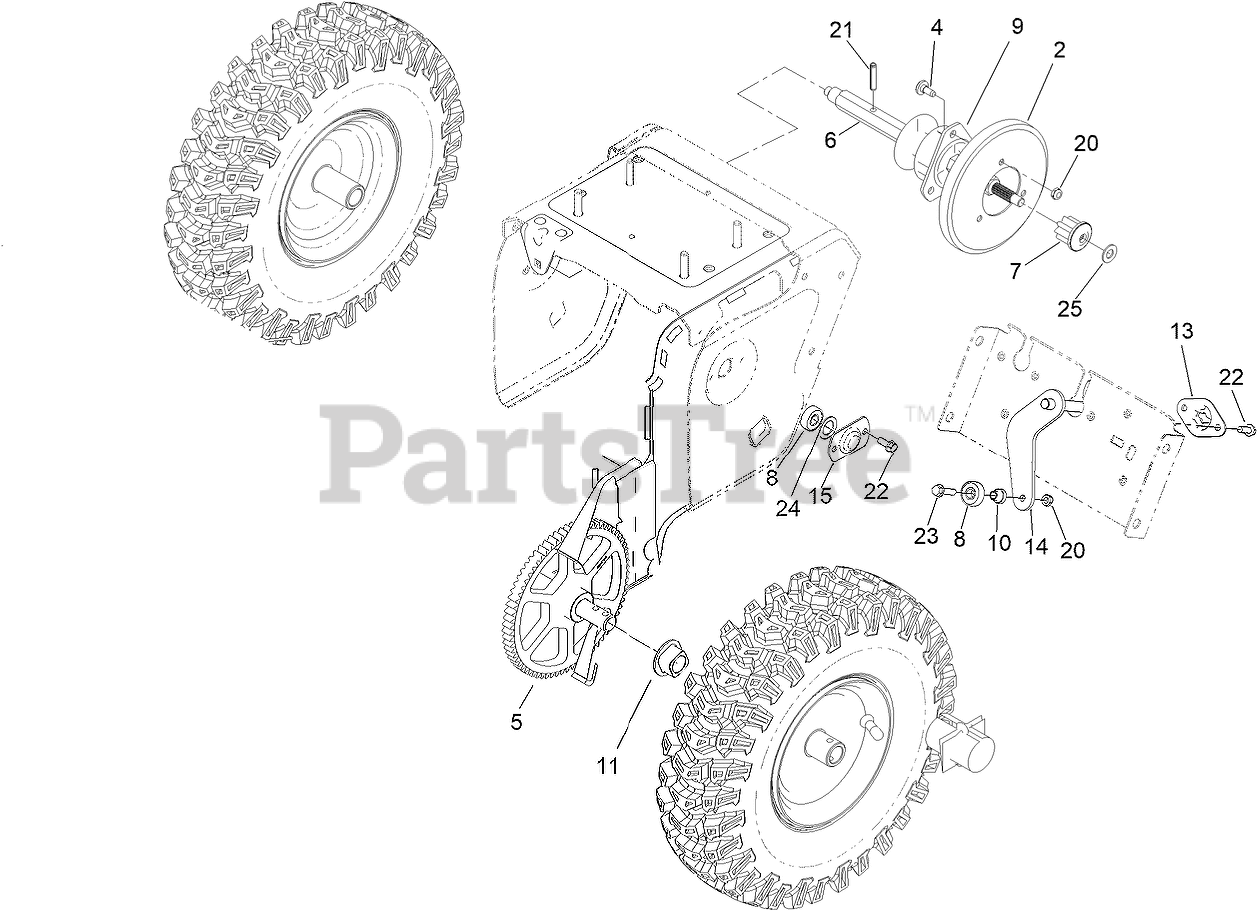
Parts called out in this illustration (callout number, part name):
2	WHEEL-FRICTION
4	SCREW-SHOULDER
5	GEAR-AXLE
6	SHAFT-HEX
7	GEAR-PINION, 8 TOOTH
8	BEARING-BALL
9	TRUNNION
10	SPACER-PLATE, SHIFT
11	BUSHING-AXLE
13	RETAINER-PLATE, SHIFT
14	SHIFT PLATE ASM
15	RETAINER-BEARING
20	NUT-HEX
21	PIN-ROLL, SLOTTED
22	SCREW-HWH
23	SCREW-HWHTF
24	WASHER-RUBBER
25	WASHER-PLAIN
